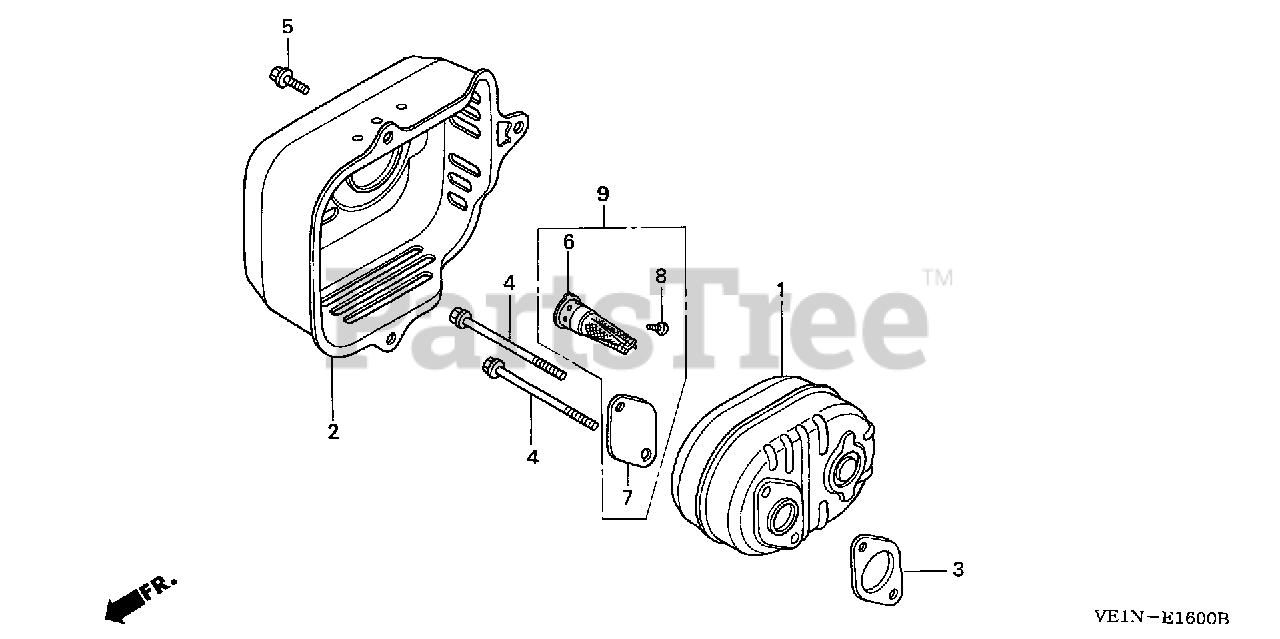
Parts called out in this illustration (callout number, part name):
1	MUFFLER
2	PROTECTOR, MUFFLER
3	GASKET, MUFFLER
4	BOLT, FLANGE (6X79) (CT200)
5	BOLT, FLANGE (6X12) (CT200)
6	ARRESTER, SPARK (OPTIONAL)
7	PLATE, ARRESTER NUMBER (TO INSTALL OPTIONAL SPARK ARRESTER)
8	SCREW, TAPPING (4X6) (TO INSTALL OPTIONAL SPARK ARRESTER)
9	ARRESTER KIT, SPARK
